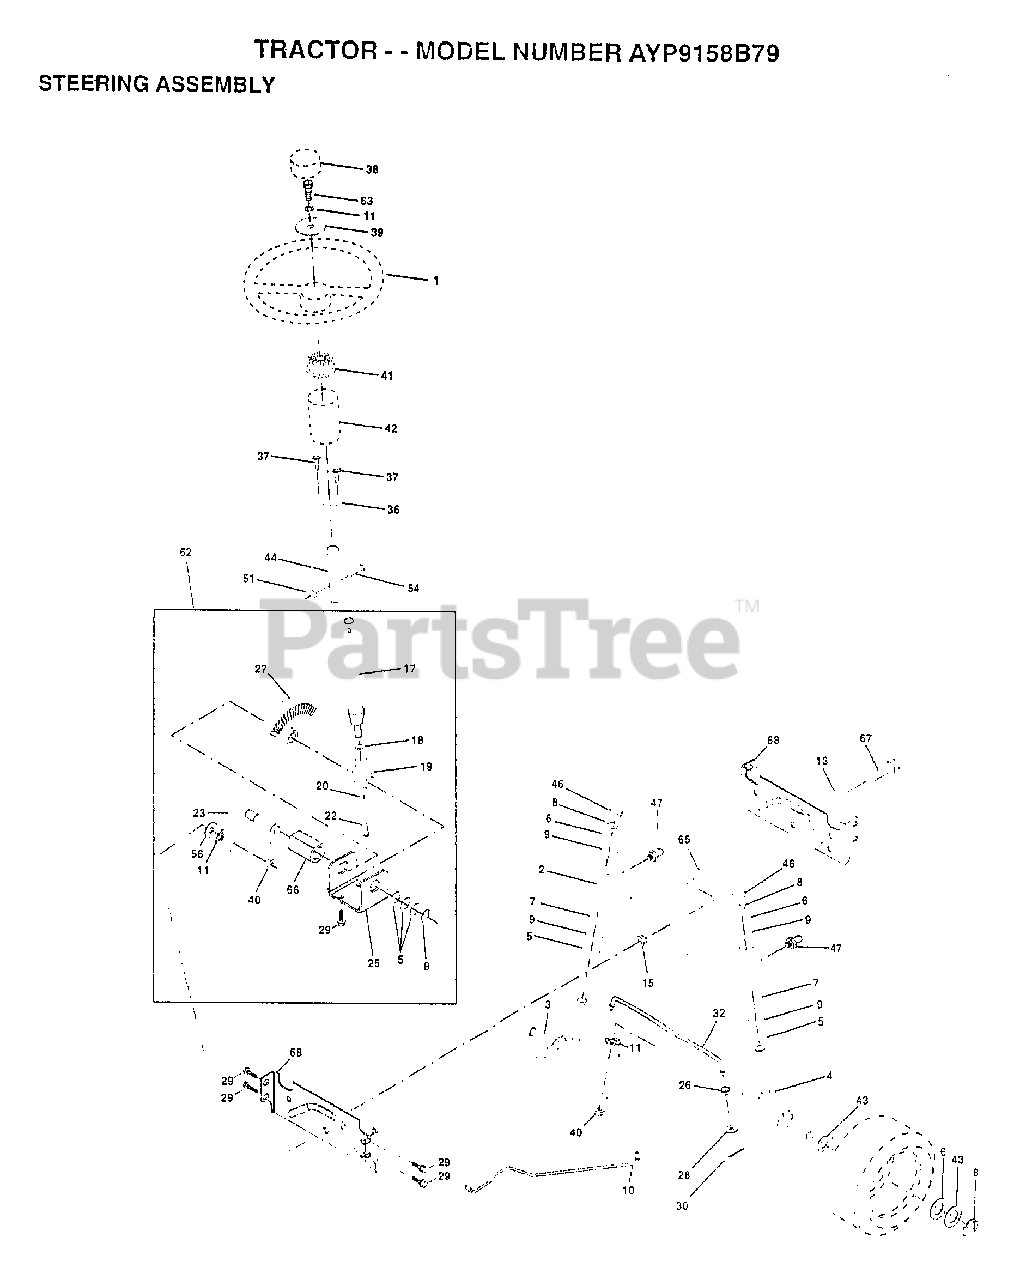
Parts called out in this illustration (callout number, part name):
1	WHEEL STR AYP BLK
2	AXLE ASM
3	SPINDLE.ASM.LH
4	"SPINDLE ASM,RH"
5	WASHER .T
6	WASHER
7	WASHER
8	RING
9	COL. SRTG. BEAR.
10	DRAGLINK-STAMPED
11	LOCKWASHER
13	BEARING AXLE
15	"NUT-LOC,FLANGE LT"
16	AXLE PIN
17	SHAFT ASM STEERIN
18	THRUST WASHER
19	SUPPORT.SHAFT
21	LOCKWASHER
22	SCREW.SCKTHD.CAP
25	BRKT-STEERING
26	BUSHING.DRAGLINK
27	GEAR SECTOR
28	WASHER
29	SCREW
30	COTTER PIN
32	TIE ROD
36	BUSHING.STEERING
37	"SCREW-TT,10-32 FL"
38	CAP STEER AYP
39	WASHER T
40	GRIPCO NUT
41	ADAPTER LT
42	BOOT.STEER.PL
43	WASHER
44	EXT SHAFT STEERIN
46	CAP
47	ZERK M
51	NUT
54	BOLT
62	KIT STEERING ASM
63	BOLT
65	SPACER AXLE
66	"BEARING-ARM,PITMA"
67	BOLT
68	BRACE AXLE
